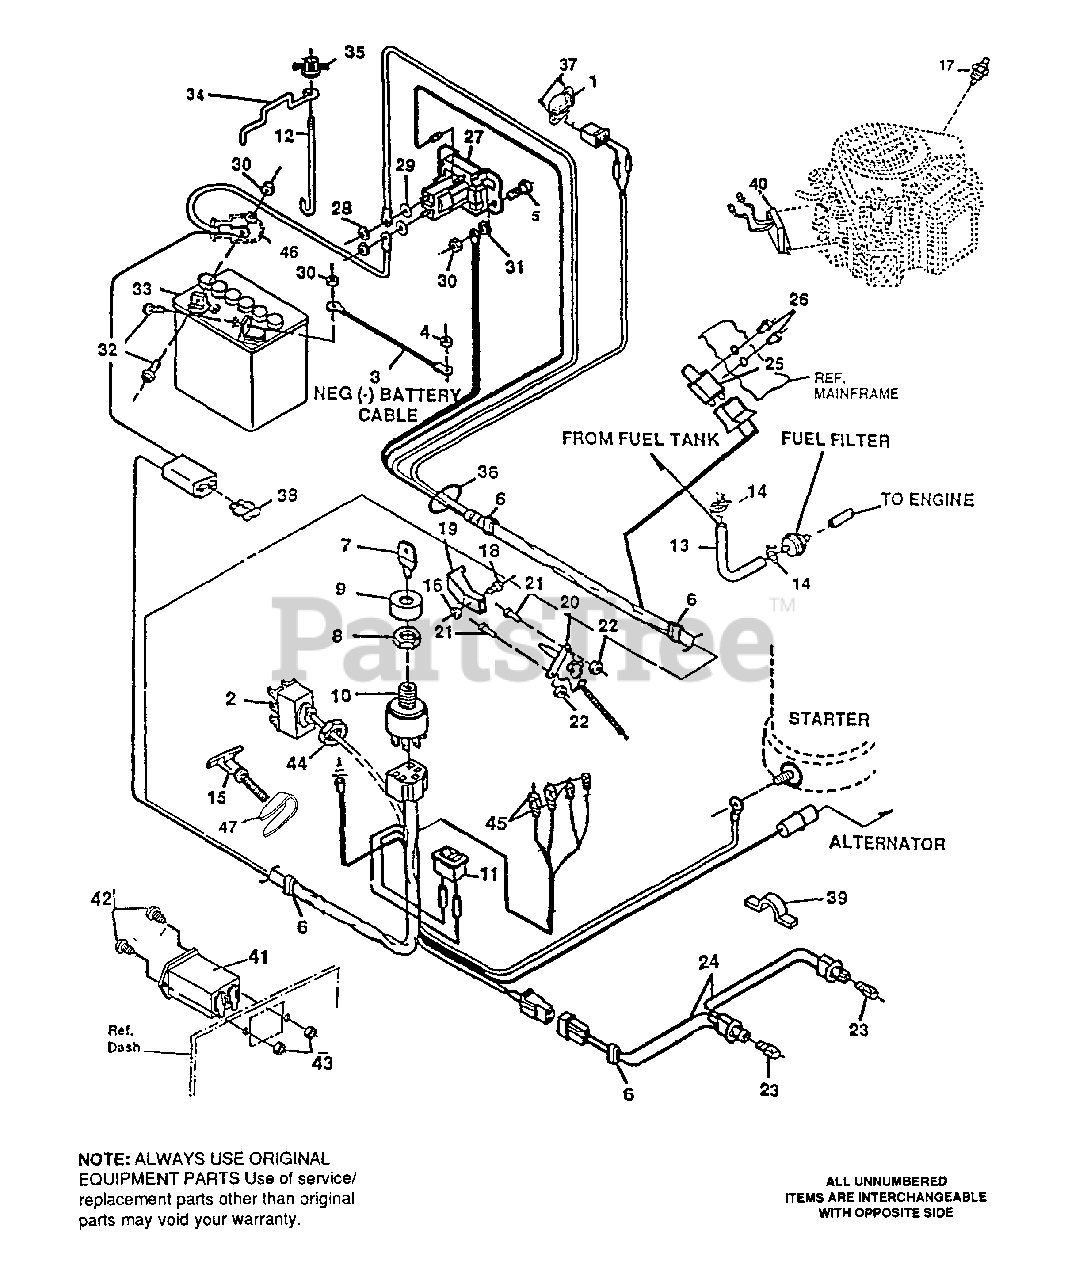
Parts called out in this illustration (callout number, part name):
1	Seat Switch
2	Switch, Elec/Clutch Actuator
3	Cable, Battery, Negative
4	Nut, Hx, Keps, 5/16-18 Thd.
5	Screw, 1/4-20 x 3/4 in.
7	Key, Ignition Switch
8	Nut, Switch
9	Boot, Switch
10	Switch, Ignition
11	Switch, Light
12	Rod, Battery Hold-Down
13	Gas Line, 10"
14	Clamp, Gas Line
15	Choke Control
16	Nut, Hex, #8-32 Thd.
17	Oil Sensor, B & S Twin Cycle
18	Screw, Ph Pn, #8-32 x 3/8 In.
19	Knob, Throttle Control
20	Throttle Control
21	Screw, 10-24x.63 Phnma Crss
22	Nut, Hx, Nylon Lock, #10-24 Thd.
23	Bulb Headlamp
24	Assembly, Light Wire
26	Screw, Pn Hd, Tap #12 x 1/2 In.
28	Nut, Hx 5/16-24 Thd.
29	Washer, Lock 5/16 In.
30	Nut, Hx, Keps, 1/4-20 Thd.
31	Nut, Hx, Ctrlk, 1/4-20 Thd.
32	Screw, 1/4-20 x .63
34	Bracket, Battery Hold-Down
35	Wingnut, 1/4-20 Thd.
36	Wiring Harness
37	Screw, 1/4-20 x 3/8
38	Fuse, 15A-32V
39	Press Clip
40	Regulator, Sen Volt B & S With Sensor
41	Miniature Hour Meter
42	Screw, #6-32x.50 Phpnma Crss
43	Nut, #6-32
45	Indicator Bulb
46	Boot, Rubber (Battery Cable)
47	Clip, Choke Control
